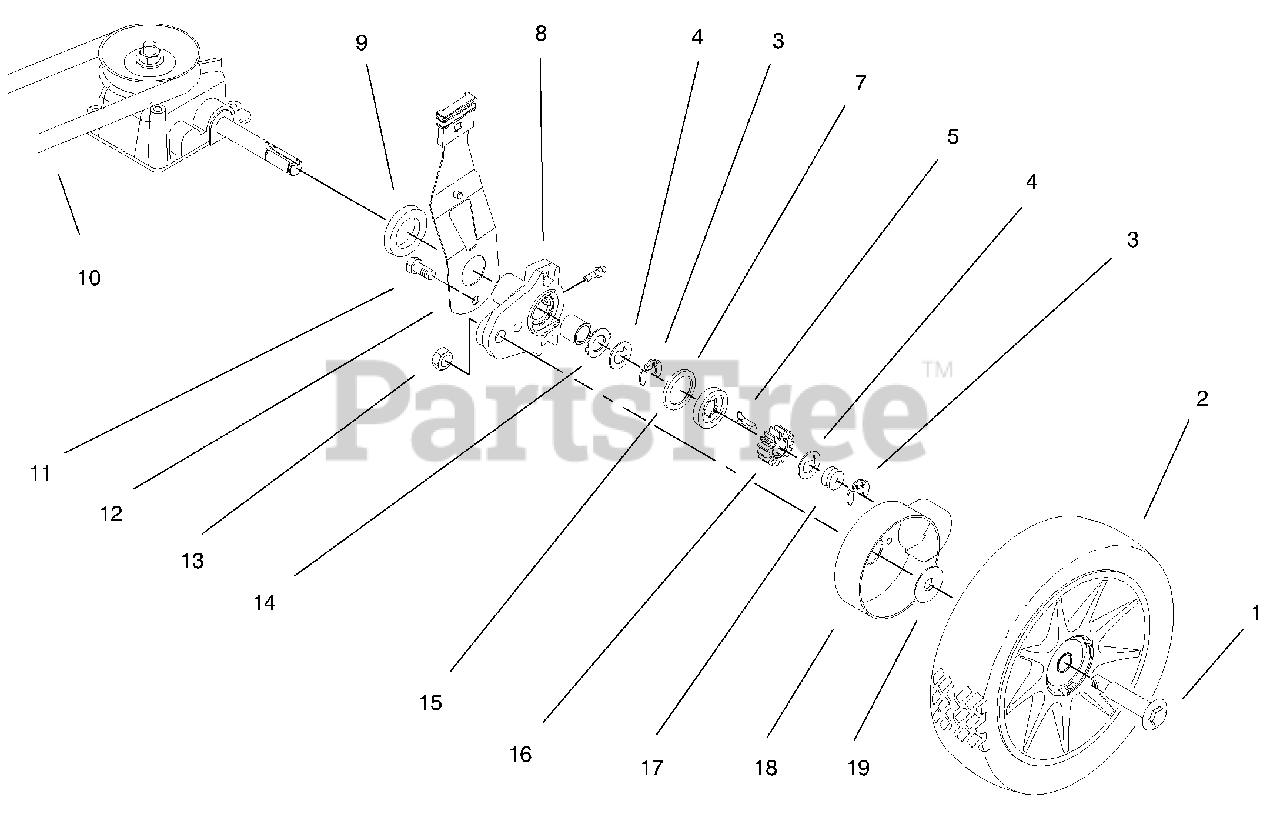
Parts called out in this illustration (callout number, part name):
1	Bolt-Shoulder
2	Wheel & Tire Ass'y 8"
3	Ring-Retaining
4	Washer-Thrust Keyed
5	Key-Rocking L.H.
7	Ring-Friction
8	Height Adj. Arm-Rear
9	Spacer-Axle Shaft
11	Screw-Hex Hd.
12	Spring Arm Ass'y
13	Nut-Lock
14	Washer-Thrust
16	Gear-Pinion
17	Spring-Compression
18	Cover-Wheel
19	Washer-Stepped
